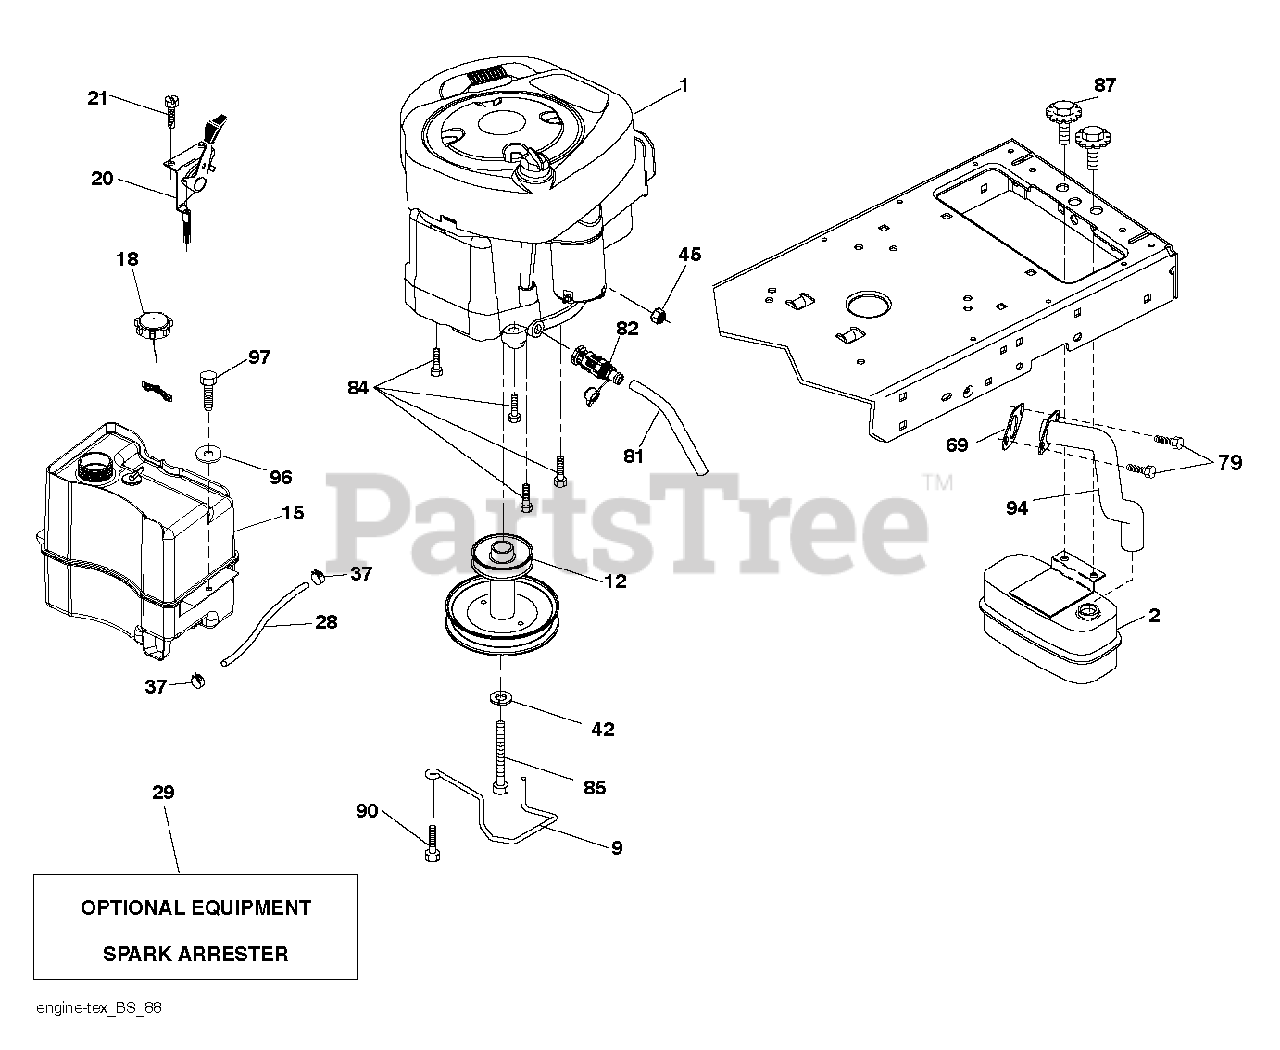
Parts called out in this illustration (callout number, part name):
2	MUFFLER.ASM.SNGL.XTNDED.DFLCTR
9	KEEPER.BELT.ENGINE.3.25 (3 2)
12	PULLEY ENGINE
15	TANK.ASSEMBL.2.5GAL.NON-EPA
18	CAP.2.25'.VENTED.TETHER .EPA
20	CONTROL.TH/CK.C.
21	SCREW.#10 X 0.750.BOS
28	LINE.FUEL.20"FRONT.EMI
29	KIT.SPARK ARRESTOR 794945 B&S
37	HOSE CLAMP
42	LOCKWASHER
45	NUT
69	REPL BY 532 27 22-93
79	SCREW.SOCKET HD.5/16-1
81	TUBE, DRAIN OIL ASM.
82	VALUE.OIL.DRAIN
84	SCREW.3/8-16
85	BOLT HEX 7/16-20X4-1/4"
87	BOLT, 5/16-18 X 1 3/4
90	SCREW 3/8-16X1
94	EXHAUST.TUBE.B&S.28/31
96	WASHER
97	SCREW HEXWSHR 1/4-20X3/4
